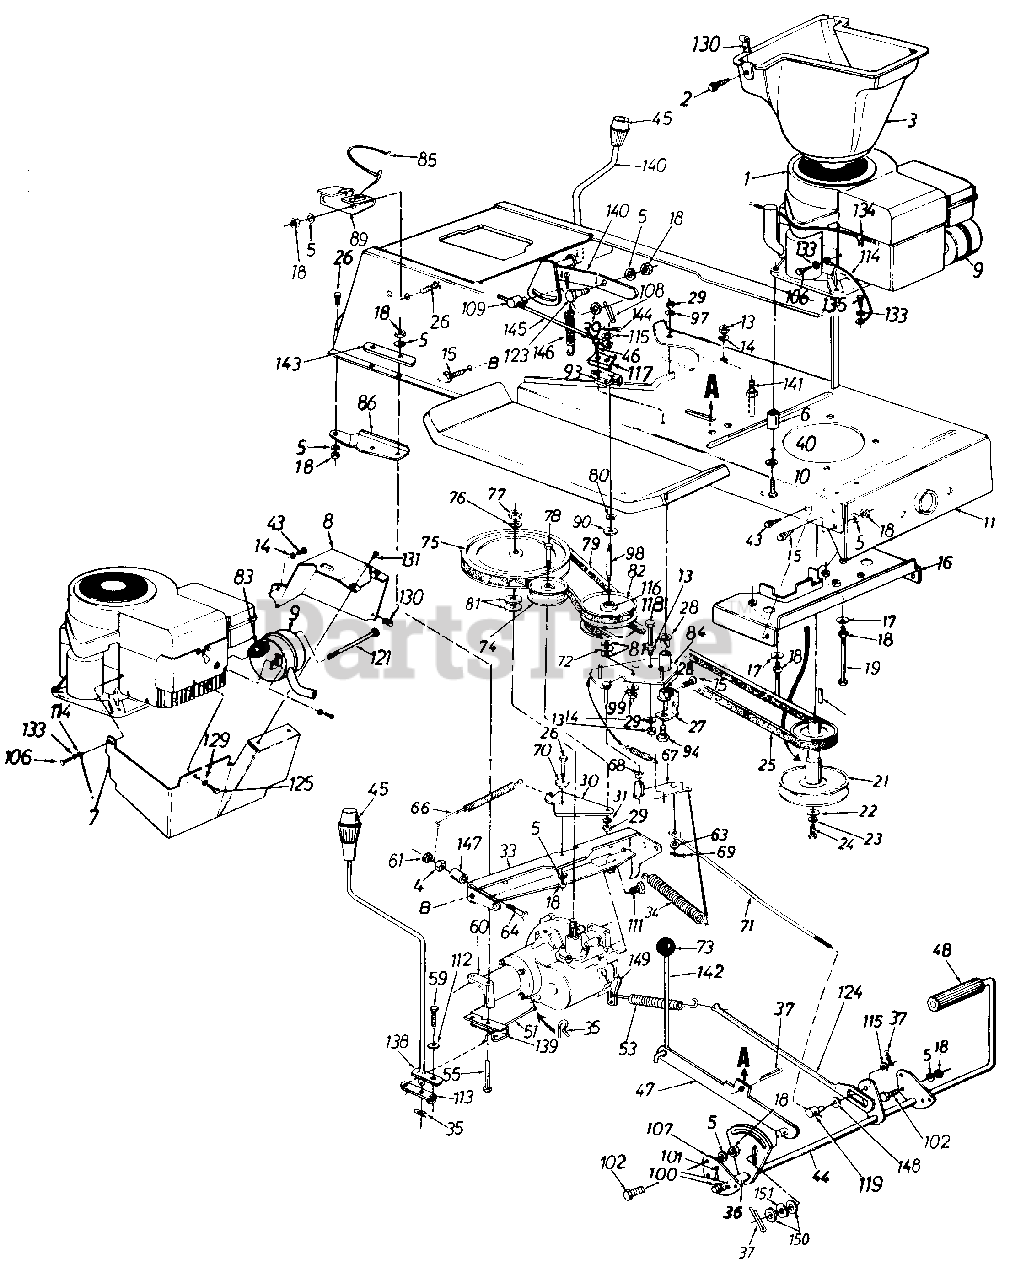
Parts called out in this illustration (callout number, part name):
1	Engine
2	Truss Mach.Scr. #10-24 x .5" Lg.
3	Air Duct
4	Hex Nut 5/16-24 Thd.
5	L-Wash. 5/16" I.D.
6	Spacer
7	Muffler Heat Shield Front
8	Muffler Heat Shield L.H.
9	Muffler
10	Hex L-Wash. Tap Scr. 3/8-16 Thd.
11	Lower Frame Ass'y.
13	Hex Nut 1/4-20 Thd.
14	L-Wash. 1/4" I.D.
15	Hex Wash. TT-Tap Scr. 5/16-18 x.62" Lg.
16	Belt Guard Brkt. Ass'y.
17	Bell-Wash. .345" I.D. x .88"
18	Hex Nut 5/16-18 Thd.
19	Hex Bolt 5/16-18 x 4.0"
21	Engine Pulley
22	Fl-Wash. 7/16" I.D. x 1.25"
23	L-Wash. 7/16" I.D.
24	Hex Bolt 7/16-20 x 1.50" Lg.
25	Variable-Speed Belt
26	Hex Bolt 5/16-18 x .75" Lg.
27	Bearing Shaft Bracket
28	Flanged Nyliner Brg. 518" I.D. x .88" Lg.
29	Hex Nut 3/8-24 Thd.
30	Idler Bracket
31	L-Wash. 3/8" I.D.
33	Transaxle Support Brkt.
34	Ext. Spring .94" O.D. x 7.58"
35	Inter. Cotter Pin
36	Spacer.63" I.D.
37	Cotter Pin 1/8" Dia. x 1.25" Lg.
39	FL-Wash. .51" I.D. x .75"
40	Fl-Wash. .406" I.D. x 1.25"
43	Hex Wash. Hd. S-Tap Scr. 1/4-20 X .501 Lg.
44	Clutch/Brake Pedal Ass'y.
45	Shift Knob
46	Truss Mach. B-Tap Scr. #10 x .5" Lg.
47	Parking Brake Lockout Brkt. Ass'y.
48	Foot Pad
51	Shift Lever Rod
53	Ext. Spring 3.6"
55	Hex Bolt 5/16-18 x 3.25"
59	Hex Bolt 1/4-28 x .62" Lg.
60	Transaxle Complete
61	Hex L-Nut 1/4-20 Thd.
63	Fl-Wash. .34" I.D. x .68" O.D.
64	Hex Wash. TT-Tap Scr. 1/4-20 x 1 .75"
66	Ext. Spring .5" O.D. x 4.35"
68	Flanged Bearing
69	Cotter Pin 3/32" Dia.
70	Shoulder Spacer .27" Lg.
71	Speed Control Link
72	Truss Bearing .56 Dia. x 1 .25"
73	Ball Knob
74	Fl-Idler Pulley 3.25" x .75"
75	"V"-Pulley
76	Bell-Wash. .567" I.D. x 1.125"
77	Hex Jam Nut 9/16-18 Thd.
78	Hex Bolt 3/8-24 x 1.75" Lg.
79	Variable Speed Belt
80	Snap Ring .56" Dia.
81	Fl-Wash. .56" I.D. x 1.0" O.D.
82	Variable Speed Pulley Ass'y. 5" O.D.
83	Gasket
90	Teflon Washer .565" I.D.
93	Safety Switch (Clutch)
94	Shld. Bolt 3/8-24 x 3.12" Lg.
97	Bell-Wash. .38" I.D. x .88"
98	Shaft
99	Bell-Wash. .39" I.D. x 1.12"
100	Fl-Wash. .64" I.D. x .94"
101	Cotter Pin 3132" Dia. x 1.0"
102	Hex Wash. Hd. Scr. 5/16-18 x.62" Lg.
106	Truss Mach. Scr. 5/16-18 x .75" Lg.
109	Ferrule
111	Hex Wash. Tap Scr. 5/16-18 x 1.25" Lg.
112	Bell-Wash. .265" I.D. x .75"
113	Shift Lever Link Ass'y.
114	Ground Wire 7.5" Lg.
115	Fl-Wash. .385" I.D. x .62"
116	Needle Brgs.
117	Switch Plate
118	Hex Bolt 1/4-20 X 3.25" Lg.
119	Ferrule
121	Shld. Bolt 7/16" Dia. x 3-5/8" Lg.
123	Shld. Bolt .437" Dia. x .162
124	Brake Rod Ass'y.
125	Hex Bolt 1/4-20 x .62" Lg.
129	Spr. Wash. .265" I.D.
130	Speed Nut #10-24 Thd.
131	Hex AB-Tap Scr. #10 x .5" Lg.
133	External L-Wash. 5/16" I.D.
134	Speed Clip
135	Hex Wash. AB-Tap Scr. 5/16" x.75" Lg.
138	Shift Lever Ass'y.
139	Shift Lever Support Brkt.
140	Speed Selector Lever Ass'y.
141	Belt Guard Pin
142	Brake Lockout Rod
144	Cotter Pin 1/8" x 3/4" Lg.
145	Speed Selector Rod
146	Ext. Spring 3.97" Lg.
147	Spacer .326" I.D. x .47"
148	Fl-Wash. 5/8" I.D. x 1.25"
149	Actuating Arm
150	Fl-Wash. .385" I.D. x .87" O.D.
151	Wave Wash. .38" I.D. x .75"
